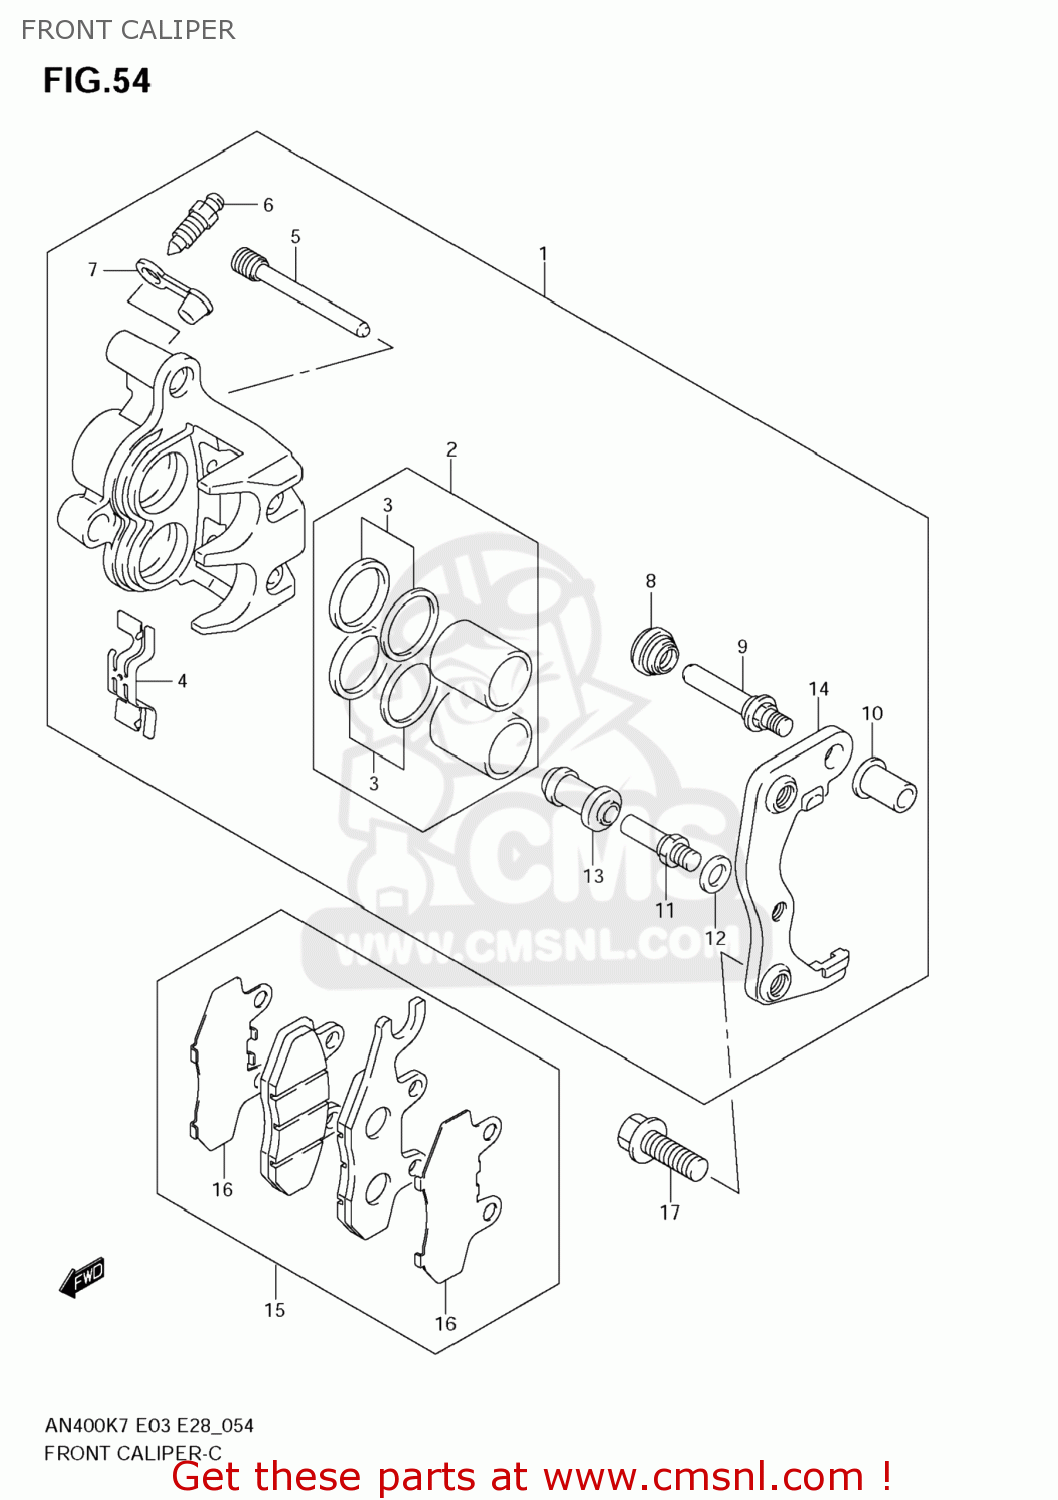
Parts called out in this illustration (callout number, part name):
1	CALIPER ASSY,FR,R
2	PISTON SET
3	SEAL SET,PISTON
4	SPRING,PAD
5	PIN,HANGER
6	BLEEDER
7	CAP,BLEEDER
8	BOOT
9	PIN,SLIDE
10	NUT
11	BOLT,PIN
12	WASHER,WAVE
13	BOOT
14	BRACKET
15	BRAKESHOE SET
16	SHIM
17	BOLT(10X25)
